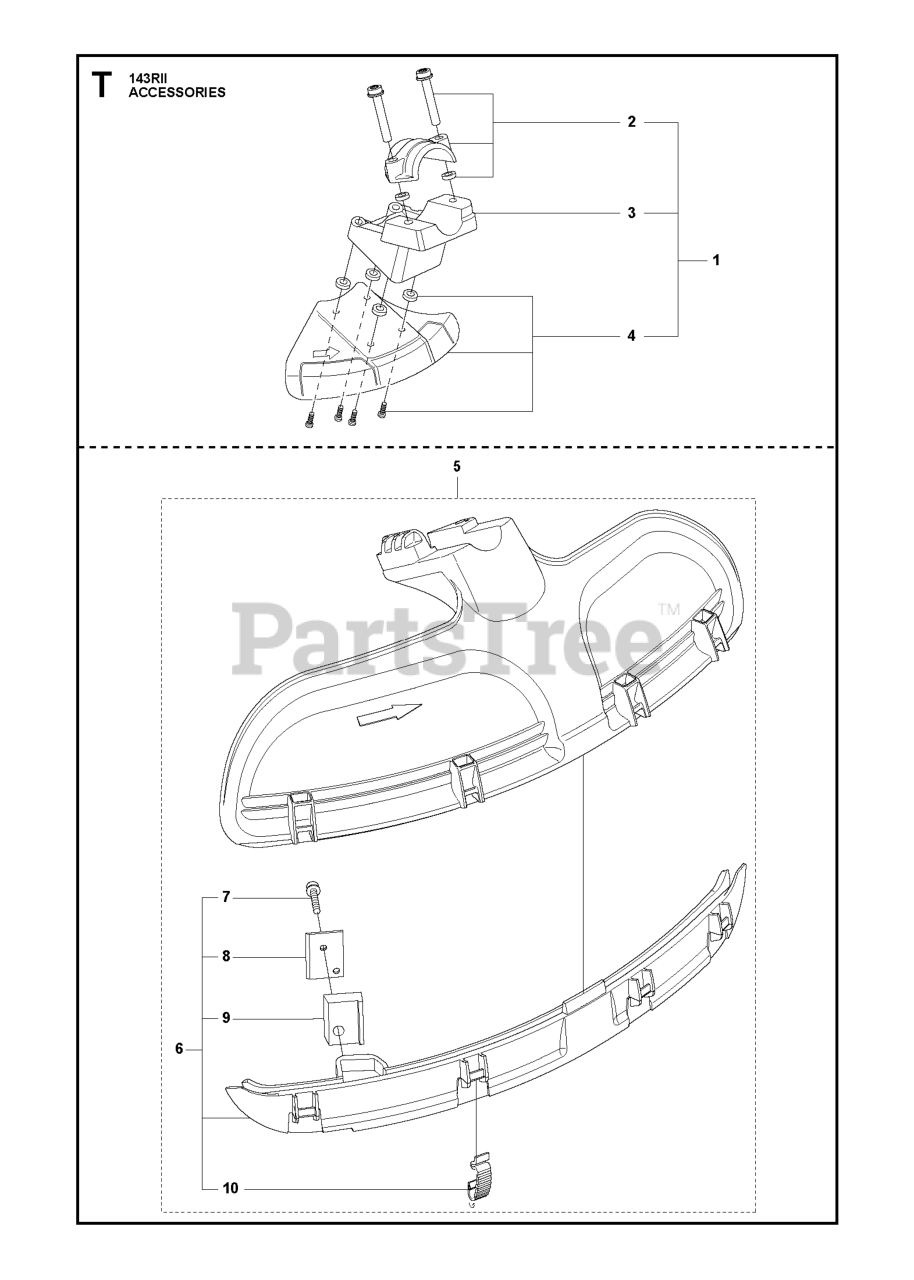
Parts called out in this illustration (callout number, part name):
5	COMBI PROTECTOR
6	SPLASH GUARD
8	LINE CUTTER
10	DISTANSBLOCK
